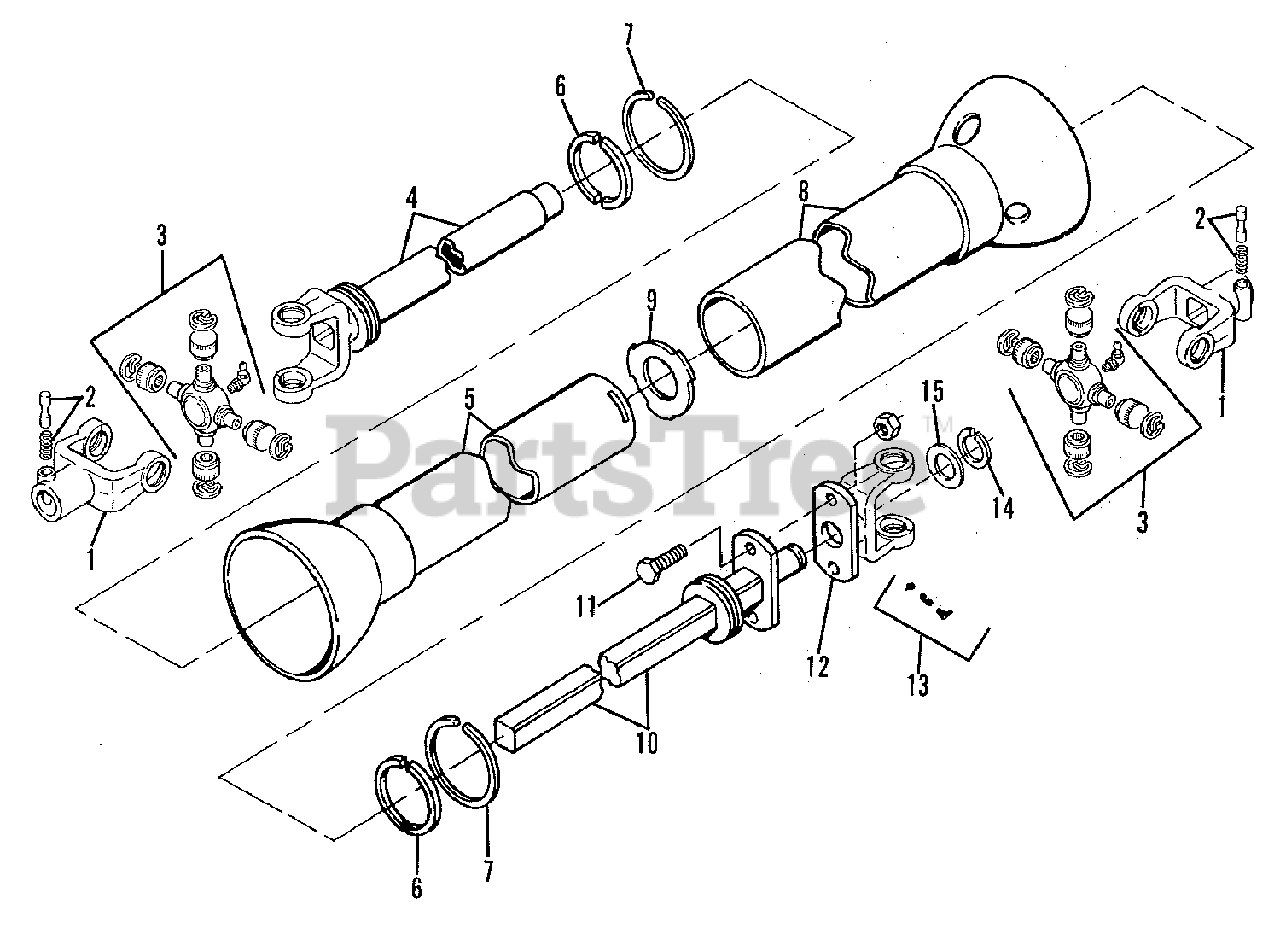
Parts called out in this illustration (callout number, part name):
1	YOKE ASSEMBLY
2	SPRING ASSEMBLY
3	U-JOINT KIT
4	TUBE ASSEMBLY (Implement End)
5	TUBE, Inner Shield)
6	RETAINER, Bearing
7	BEARING, Shaft
8	TUBE, Outer Shield
9	CENTRALIZER, Tube
10	SHAFT ASSEMBLY, Shear Flange
11	BOLT, Shear
11	NUT, Lock, 1/4NC
12	YOKE ASSEMBLY, Shear Flange
13	FITTING KIT, Lube
14	RING, Shaft Retaining
15	WASHER, Shaft
